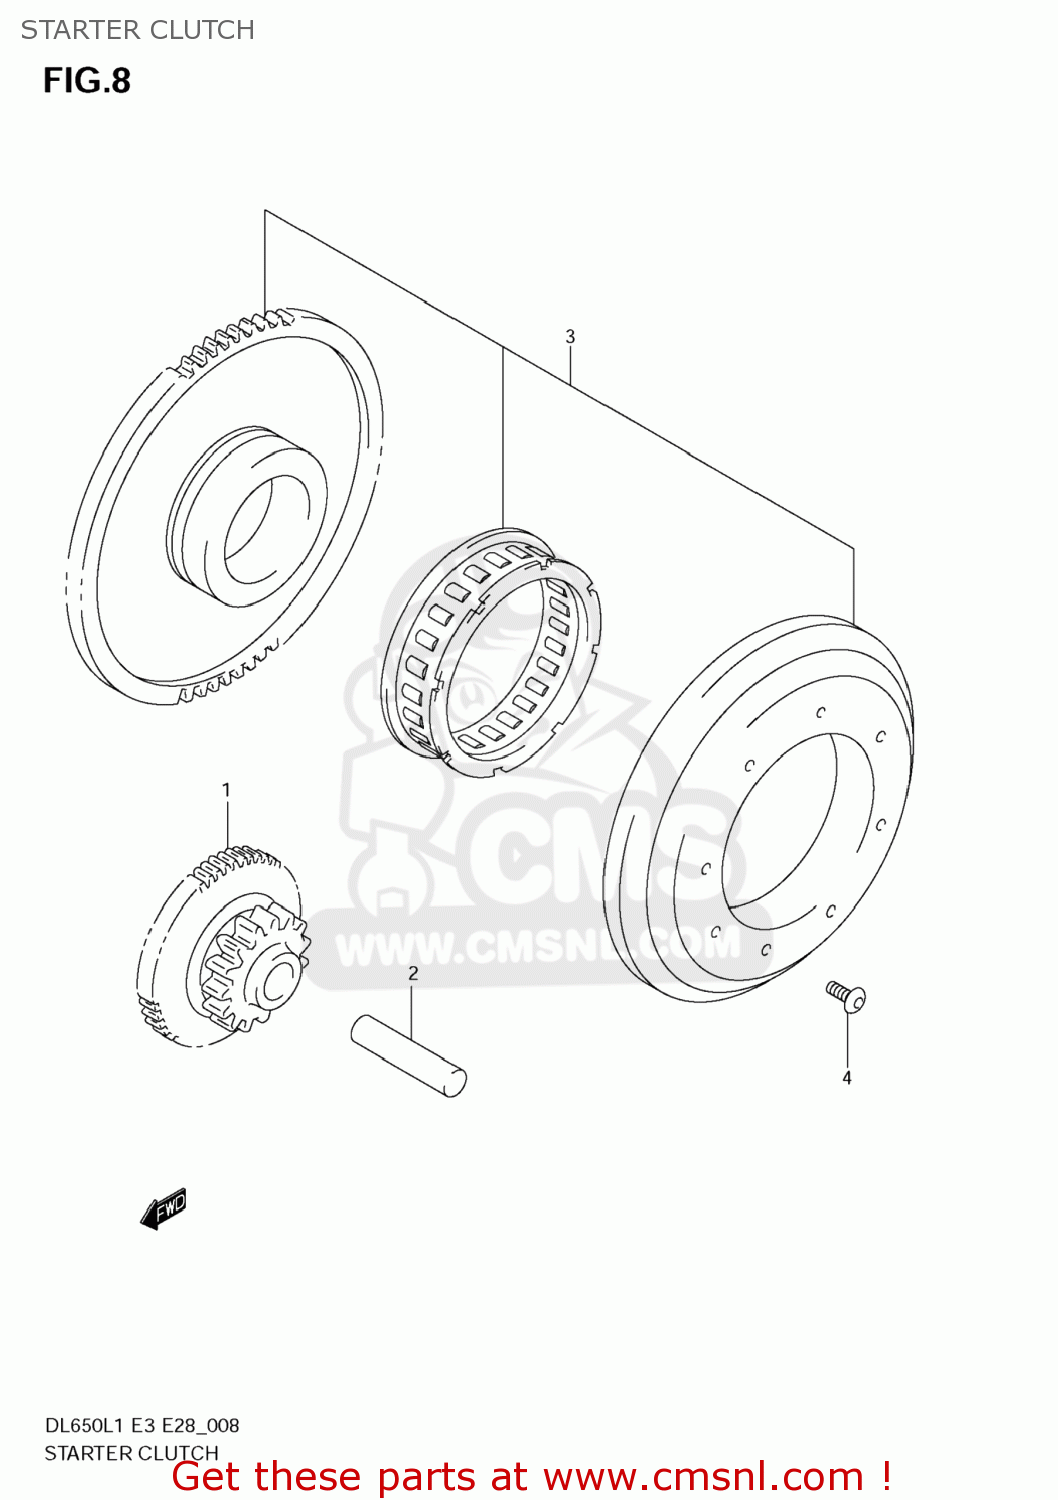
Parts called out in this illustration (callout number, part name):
1	GEAR,STARTER IDLE
2	PIN(8X12X45.5)
3	CLUTCH SET,STARTER
4	SCREW(8X16)
